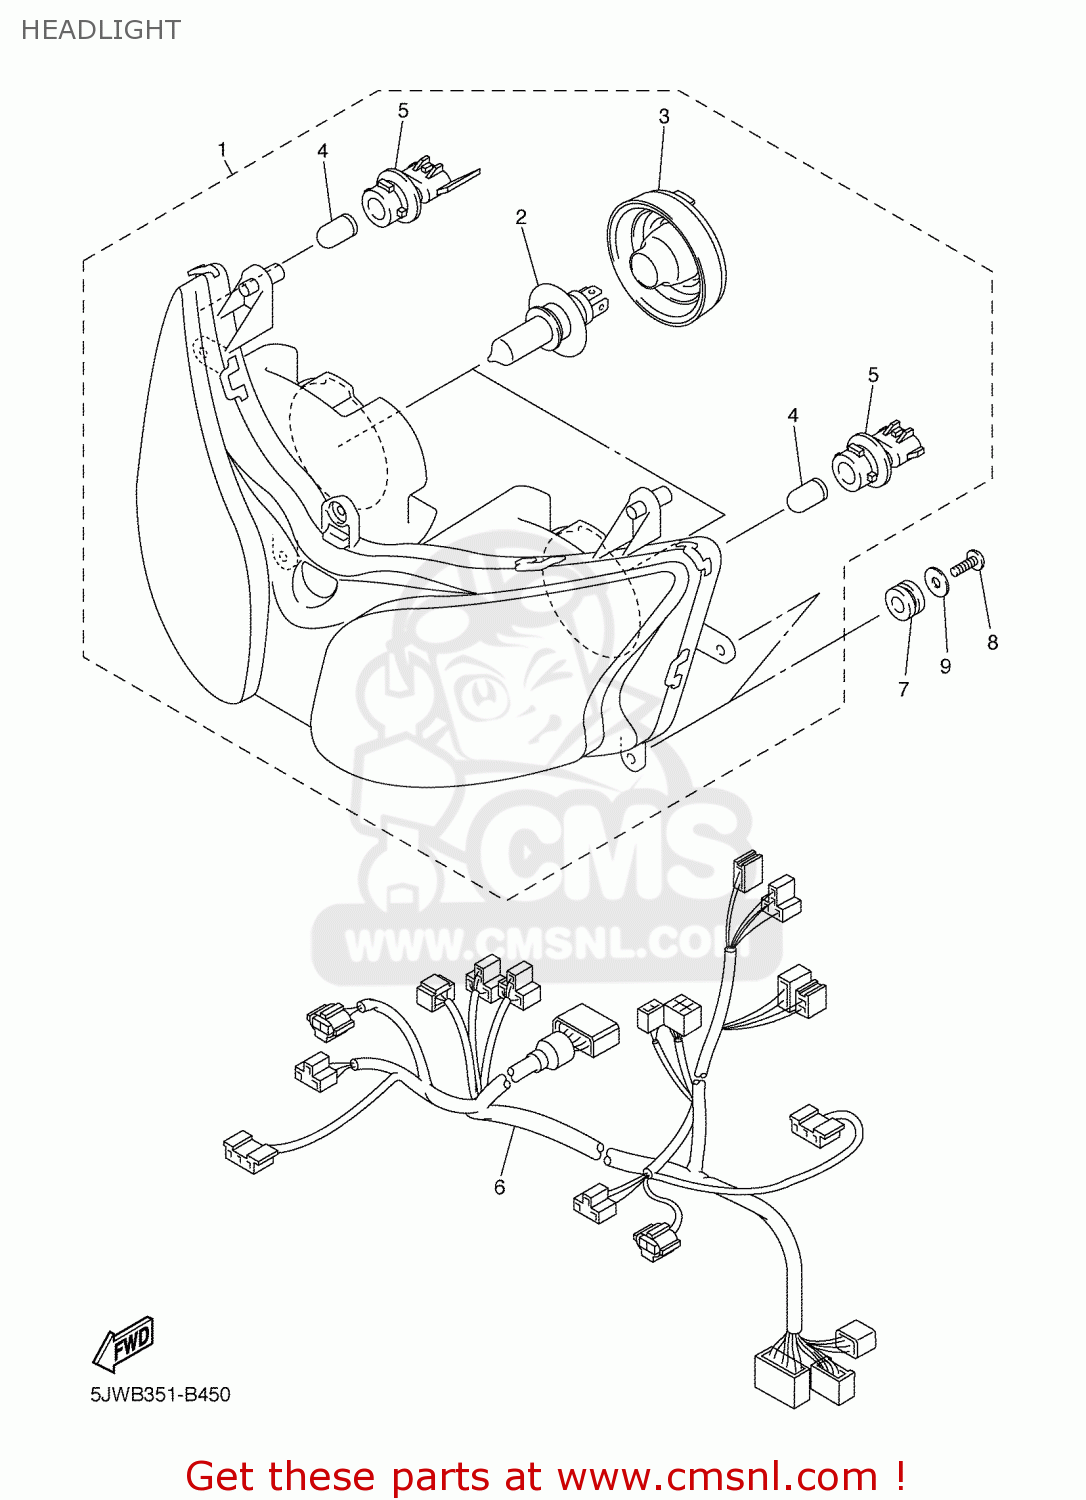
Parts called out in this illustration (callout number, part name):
01	HEADLIGHT ASSY
02	BULB (12V 60/55W)
03	COVER, SOCKET
04	BULB
05	SOCKET, PILOT LIGHT
06	CORD, HEADLIGHT
07	DAMPER
08	SCREW, TAPPING(4MV)
09	WASHER PLATE 803835240000
